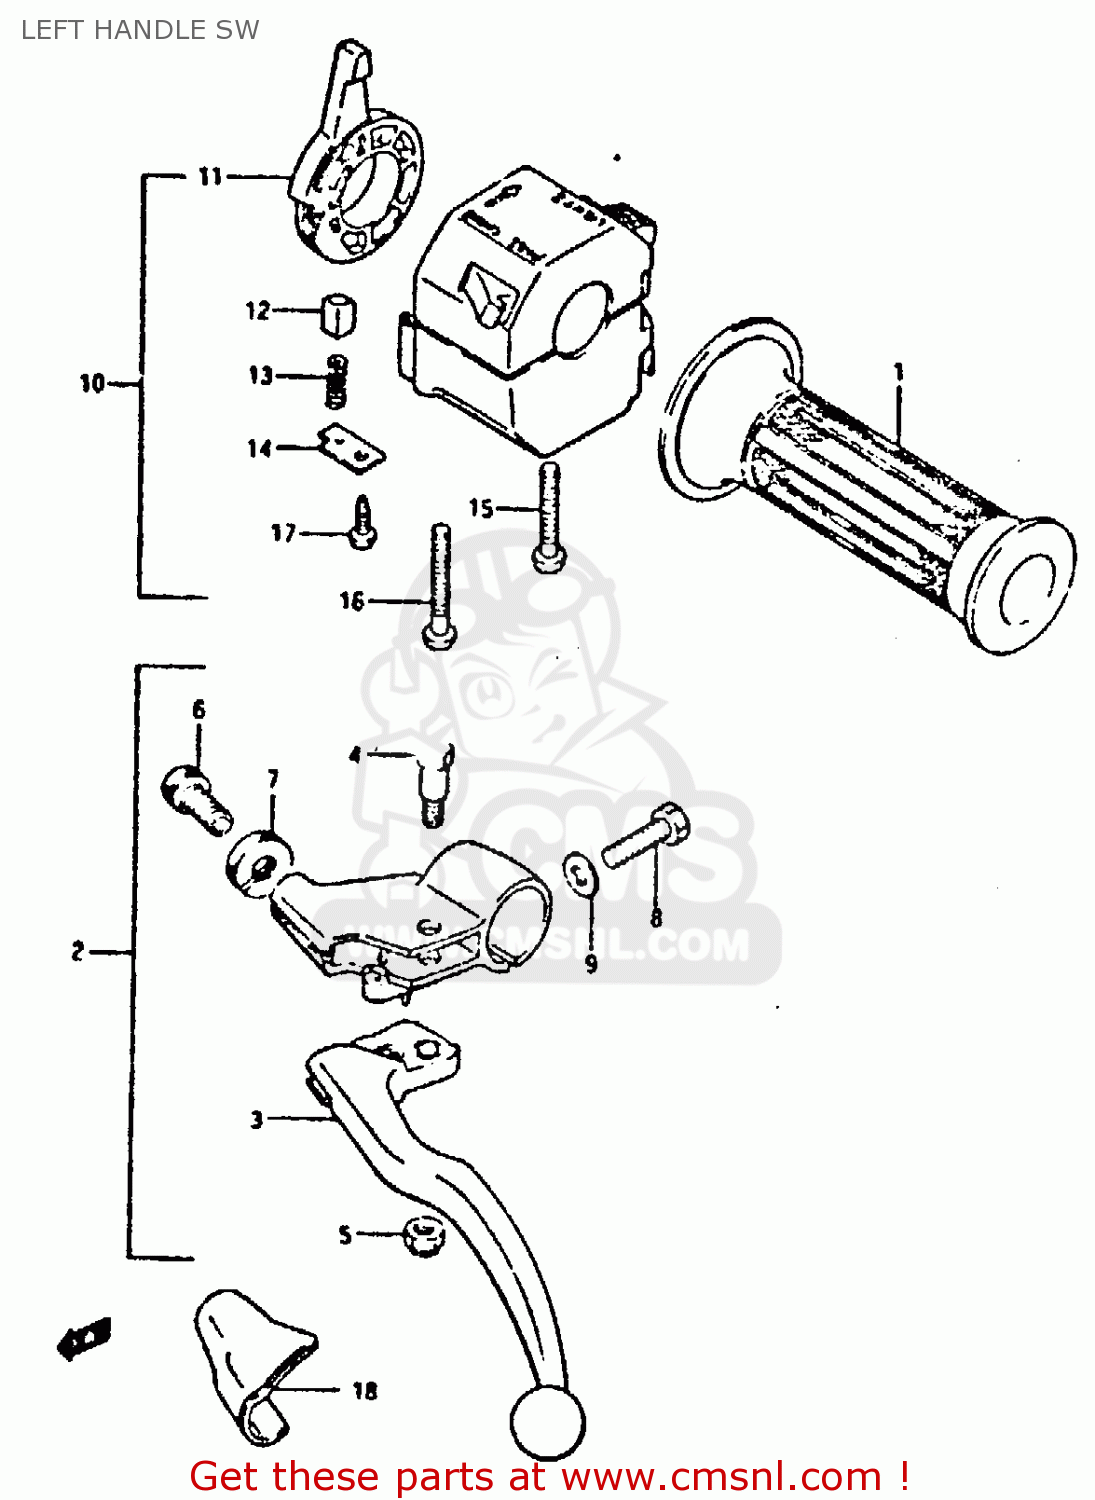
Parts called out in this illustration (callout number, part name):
1	GRIP,L
2	0.3
3	LEVER,CLUTCH
4	BOLT,LEVER PIVOT
5	NUT
6	ADJUSTER,CABLE
7	NUT,CABLE ADJUSTER LOCK
8	BOLT
9	WASHER
10	SWITCH ASSEMBLY,HANDLE,LEFT
11	LEVER,CHOKE
12	PIECE,SLIDE
13	SPRING
14	PLATE
15	SCREW
16	SCREW, 5X45
17	SCREW
18	COVER,CLUTCH LEVER
